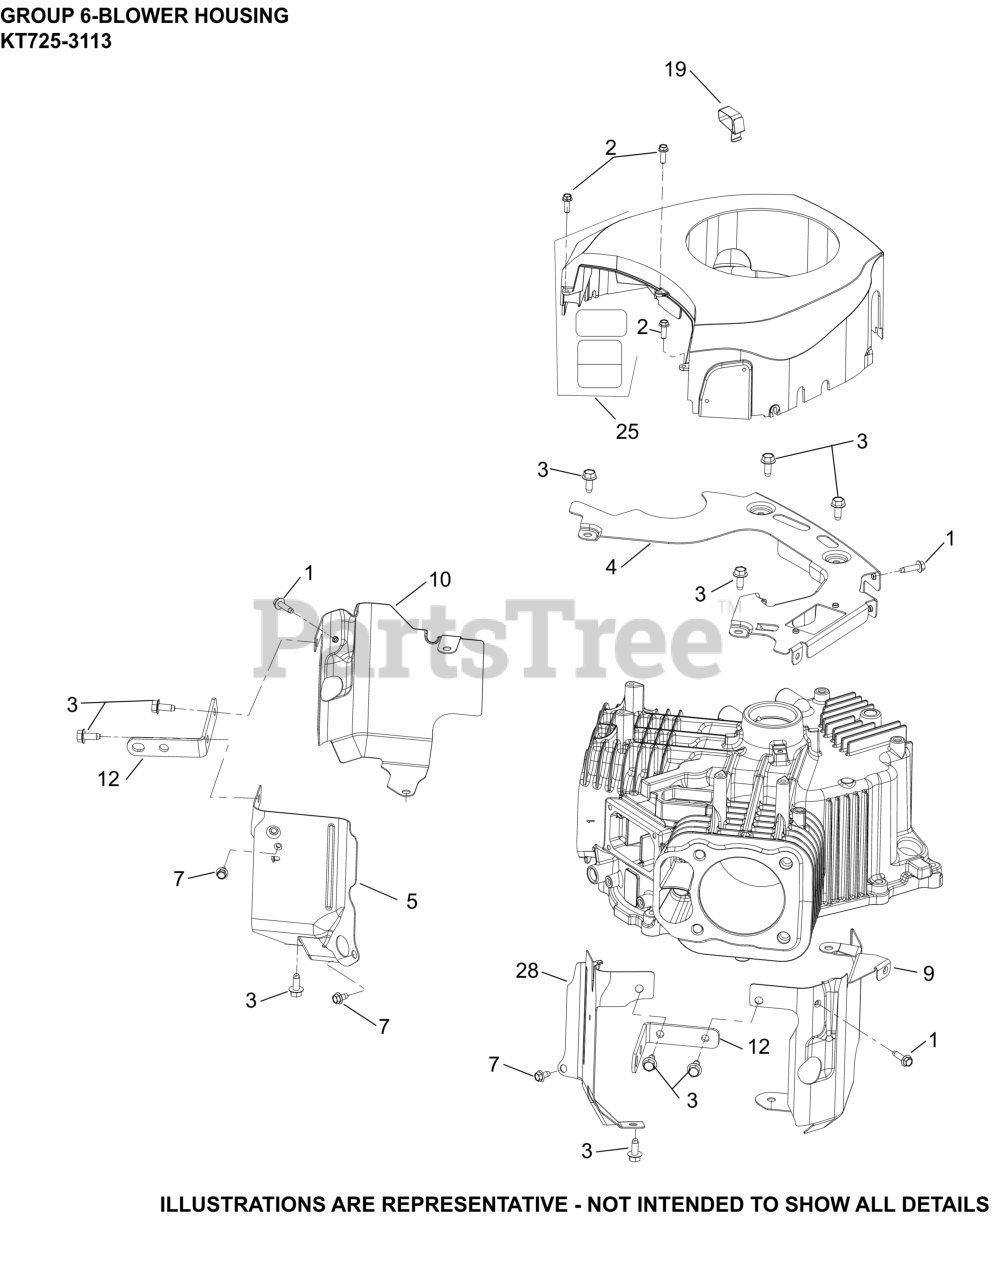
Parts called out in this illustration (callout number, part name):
1	SCREW, THD FRM-USE 25 086 473-S
2	SCREW, HI-LOW
3	SCREW, THREAD FORMING
4	PLATE, BACKING
5	BAFFLE, VALLEY #1
7	SCREW, THREAD FORMING
9	BAFFLE, LEFT BARREL
10	BAFFLE, RIGHT BARREL
12	STRAP, LIFTING
19	CLIP, BLOWER HOUSING
25	KIT, BLOWER HOUSING
28	BAFFLE, VALLEY #2
